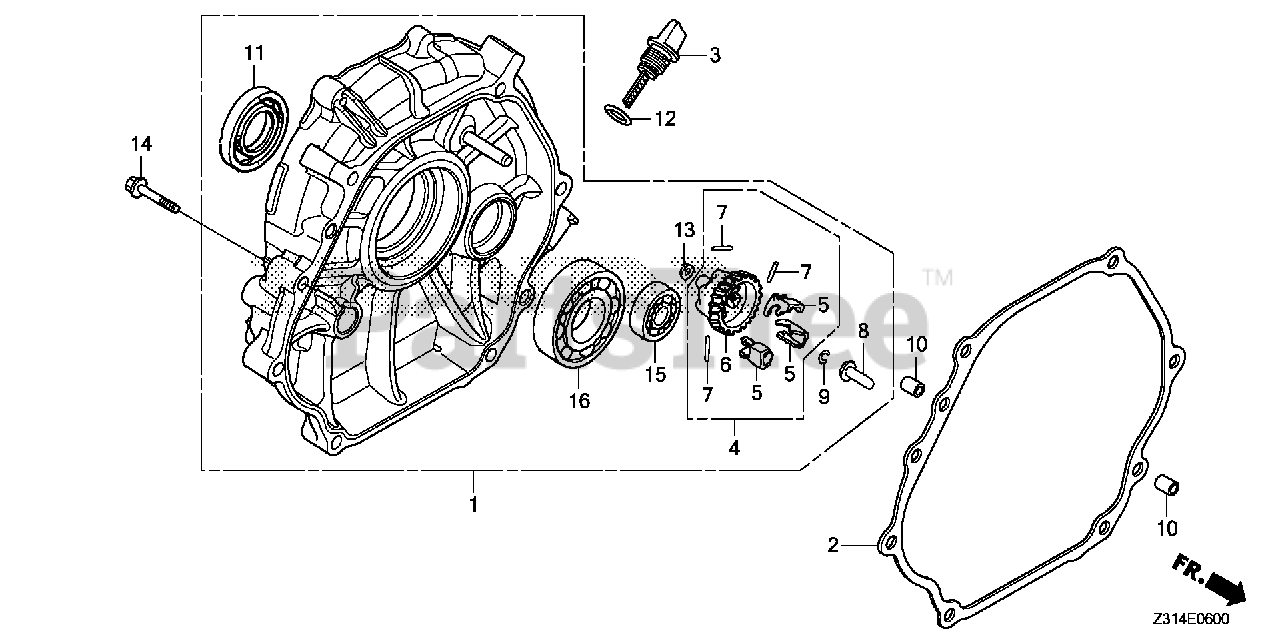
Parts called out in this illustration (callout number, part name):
1	COVER ASSY., CRANKCASE (E-TYPE)
2	GASKET, CRANKCASE COVER
3	CAP, OIL FILLER
4	GOVERNOR ASSY.
5	WEIGHT, GOVERNOR
6	HOLDER, GOVERNOR WEIGHT
7	PIN, GOVERNOR WEIGHT
8	SLIDER, GOVERNOR
9	CLIP, GOVERNOR HOLDER
10	PIN, DOWEL (8X12)
11	OIL SEAL (35X52X8) (NOK)
12	O-RING (26X2.7)
13	WASHER, PLAIN (6MM)
14	BOLT, FLANGE (8X40)
15	BEARING, RADIAL BALL (6202)
16	BEARING, RADIAL BALL (6207)
